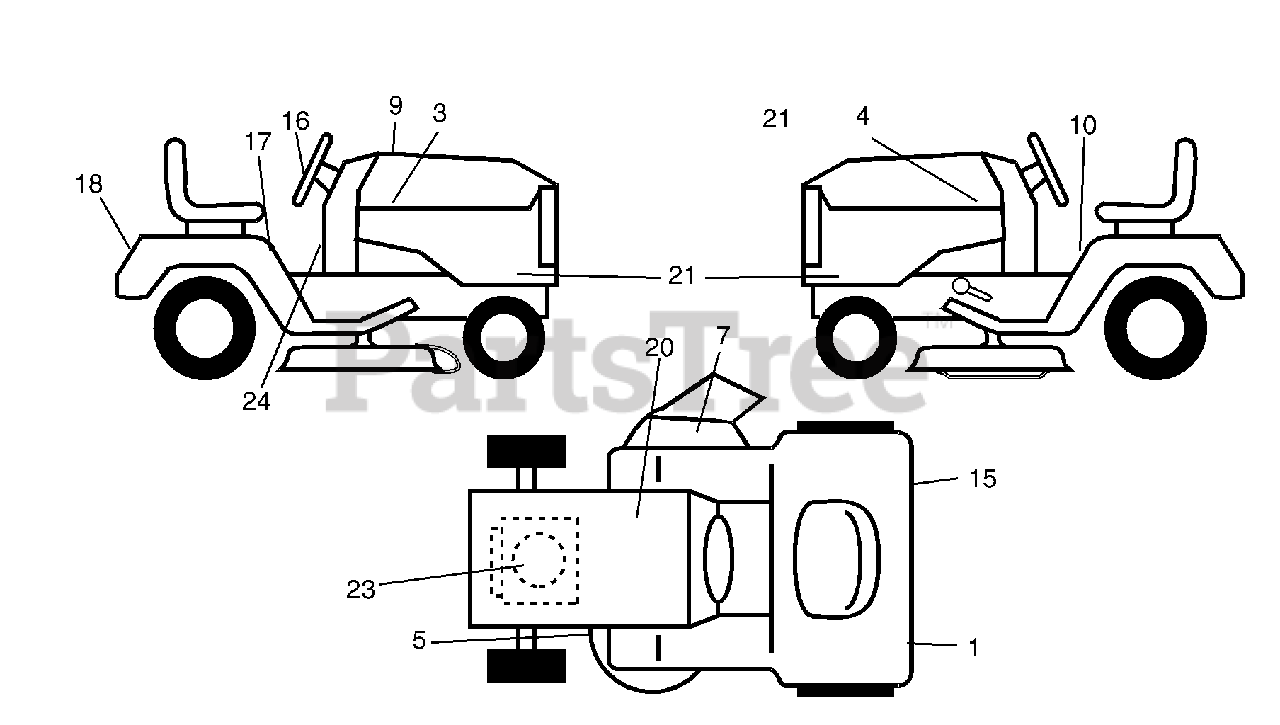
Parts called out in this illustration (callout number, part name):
1	Reflector, LH
3	Decal, Hood RH
4	Decal, Hood LH
5	Decal, Deck Sch.
7	Decal, Deck "B" "42"
9	Decal, Replacement Hood
10	Decal, Fender, Danger
15	Decal, Reflector, RH
16	Decal, Steering Wheel
17	Decal, Fender, Operator Instructions
18	Decal, Fender
20	Decal, Battery
21	Decal, Hood, Side Panel
23	Decal, Engine
24	Decal, Dash
